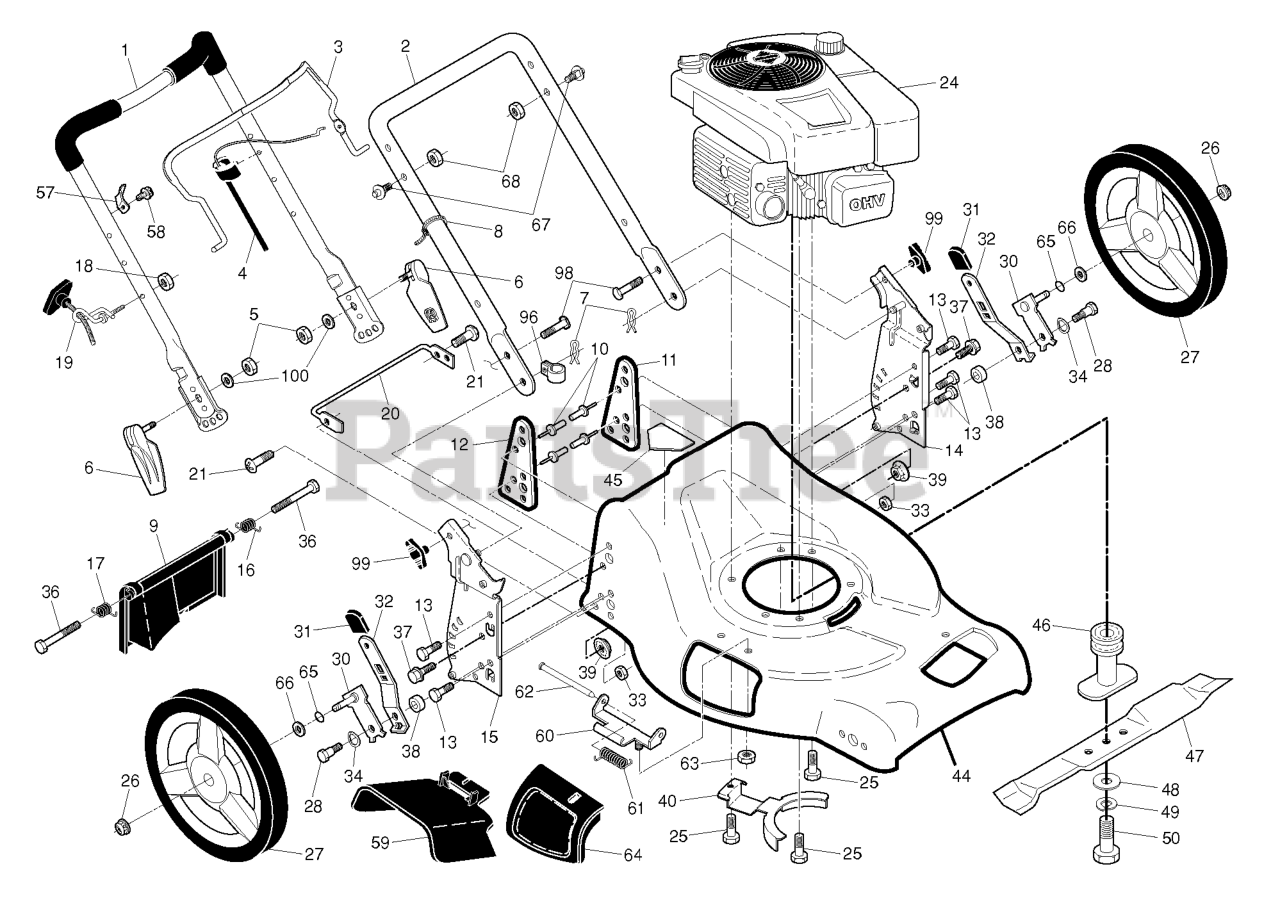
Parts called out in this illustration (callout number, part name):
1	HANDLE.ASM.UP.W/ADJ.BKT.21FGD
2	HANDLE.LOWER.21.NB.GREY
3	BAIL.CONTROL.MZR.BS.ORANGE
4	CABLE.ASM.ZONE.CONTROL
5	Locknut, Hex 1/4-20
6	QUICK.ASM.RELEASE.BLACK
7	HAIRPIN COTTER
8	TIE GUIDE
9	REAR DOOR ASSEMBLY
10	RIVET BLIND
11	SUPPORT BRACKET LH
12	BRACKET.SUPRT.RH.21.FWGD
13	SCREW 14-20 X 5/8
14	BRACKET.ASM.HDL.LT.21FGD.HW.OR
15	BRACKET.ASM.HDL.RT.21FGD.HW.N
16	SPRING.REAR.DOOR.EZ.21.LT
17	SPRING.REAR.DOOR.EZ.21.RT
18	NUT
19	RB GUIDE.ROPE.STD.BLK.ZIN WSL
20	FOOT.GUARD.21.DOM/FGD.CE.10
21	SCREW
25	BOLT 3/8-16X1-1/8
26	NUT.HEX.FLANGE.3/8-16.LOCKNUT
27	WHEEL ASSY
28	SHOULDER BOLT 5/16-18
30	ARM.ASM.AXLE.REAR.5/9.POS.BZP
31	SELECTOR KNOB
32	SELECTOR SPRING
33	NUT.71038.31-18.HEX.NYLOCK
34	WASHER.CURVED.CYLINDRICAL
37	BOLT.FIN.HEX.5/16-18X3/4
38	SPACER.HEIGHT.ADJUSTER
39	NUT.FLANGE.5/16
40	BRACKET.ENG/BELTKEEPER
44	KIT.HSG.21.FGD.MC.ORG.CE SYM
45	DECAL.INTERNATIONL.CUTFINGER
46	RB ADAPTER.BLADE.25MM.VS.LOW
47	BLADE.21.PUSH
48	WASHER,HARDEN
49	LOCKWASHER
50	SCREW, HEX HD 3/8-24 X 1-3/8
57	BRACKET.UPSTOP.RT
59	DEFLECTOR.CLIPPIN.21.FGD
60	BRACKET.ASM.HINGE.21.FWGD.
61	SPRING.TORSION
62	ROD.HINGE.21
63	LOCKNUT.NYLOC.1/4-20
64	DOOR.MULCH.21.REAR.FWGD
65	O-RING..070X.487.NEOPRENE
66	WASHER.FLAT.1/2
67	STUD.QUICK.ADJUST
68	NUT.LOCK.5/16-18
96	CLIP.CABLE.BLK
98	BOLT
99	KNOB, DEFLECTOR
100	WASHER.20X8.5
